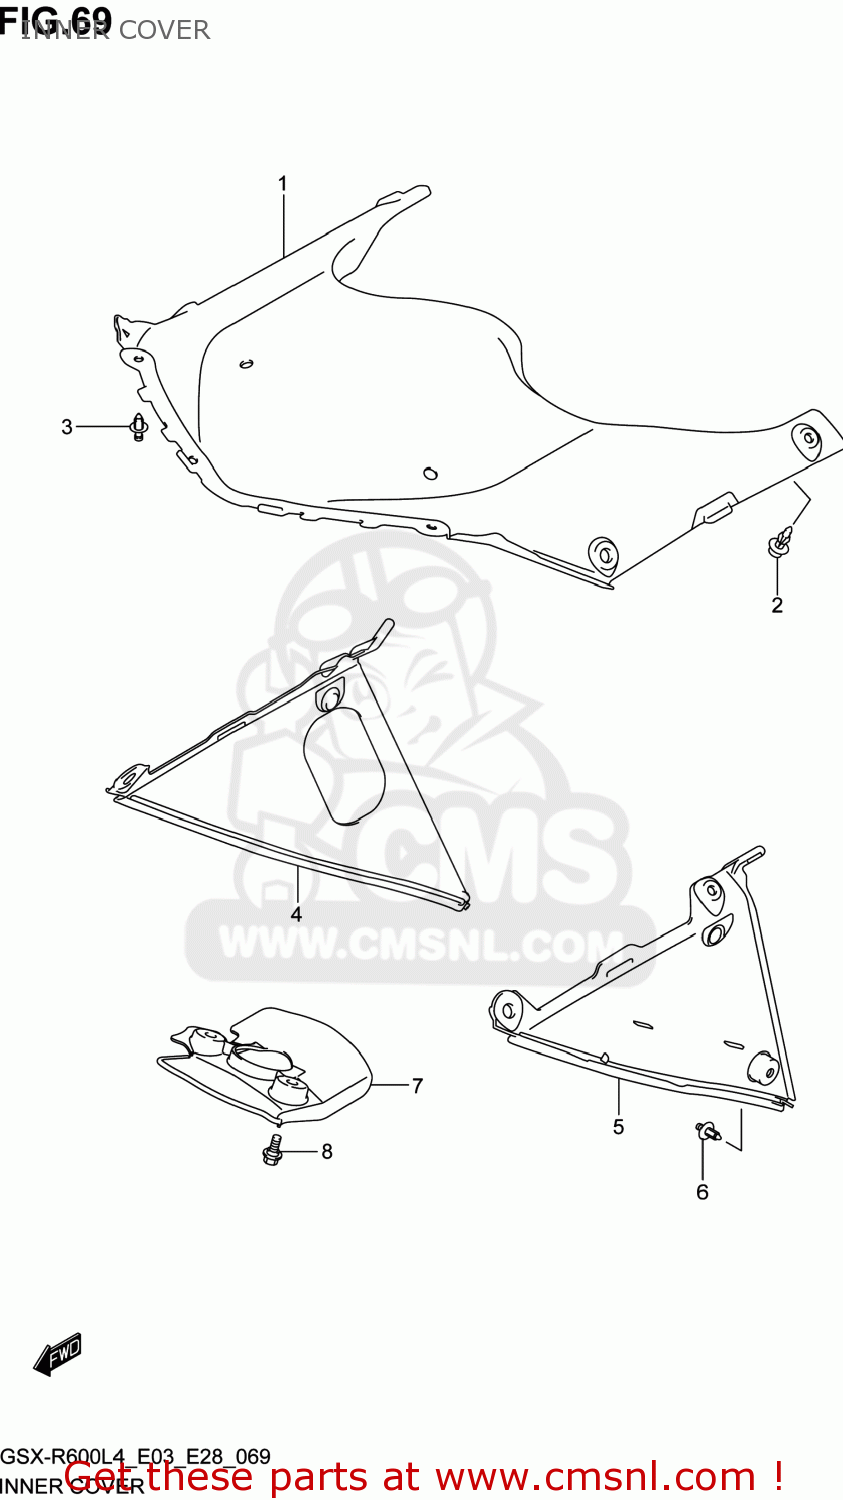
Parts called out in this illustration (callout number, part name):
1	COVER,BODY COWLING
2	CLIP(BLACK)
3	CLIP(BLACK)
4	COWLING,UNDER INNER,R
5	COWLING,UNDER INNER,L
6	CLIP
7	COVER,LWR BRACKET
8	BOLT(6X12)
